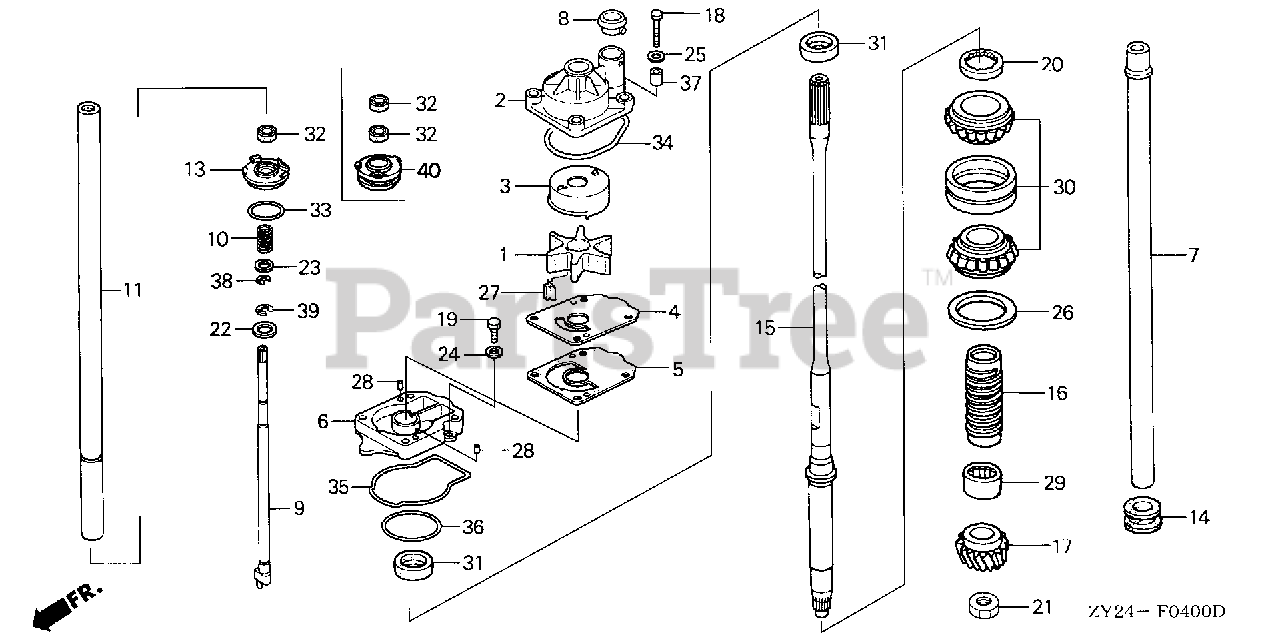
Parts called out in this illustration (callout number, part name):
1	IMPELLER, PUMP
2	HOUSING, IMPELLER
3	LINER, PUMP
4	COVER, IMPELLER
5	GASKET B, IMPELLER
6	HOUSING, WATER PUMP
7	TUBE, WATER (XL)
8	RING, WATER TUBE SEAL
9	ROD, SHIFT
10	SPRING, SHIFT ROD
11	ROD A, SHIFT (XL)(C/R)
13	HOLDER, SHIFT ROD
14	GROMMET, EXTENSION CASE
15	SHAFT, VERTICAL (XL)
16	SLINGER, OIL
17	GEAR, PINION
18	BOLT, HEX. (8X60)
19	BOLT, HEX. (6X16)
20	NUT, LOCK (64MM)
21	NUT, HEX. (18MM)
22	WASHER (14.2X30.5)
23	WASHER, PLAIN (12MM)
24	WASHER, PLAIN (6MM)
25	WASHER (8MM)
26	SHIM A, GEAR (0.10)
26	SHIM B, GEAR (0.15)
26	SHIM C, GEAR (0.30)
26	SHIM D, GEAR (0.50)
27	KEY, WOODRUFF
28	PIN, DOWEL (6X10)
29	BEARING, NEEDLE (32X46X37)
30	BEARING, TAPER ROLLER (30X62X40)
31	SEAL, WATER (26X42X7)
32	SEAL, WATER (12X21X6)
34	O-RING, WATER PUMP
35	O-RING, WATER PUMP HOUSING
36	O-RING (69.1X2.4)
37	COLLAR, DISTANCE
38	E-RING (10MM)
39	E-RING (12MM)
